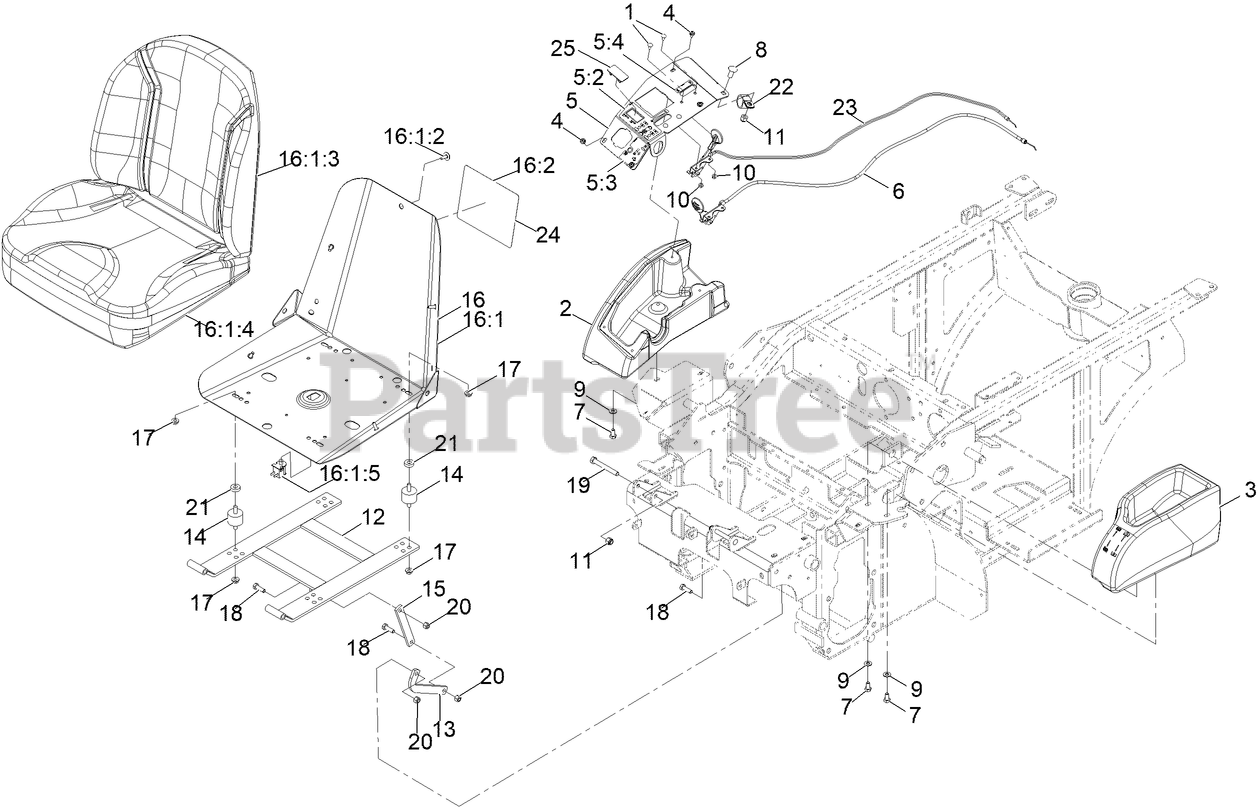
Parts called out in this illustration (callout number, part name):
1	BOLT-CARR
2	CONSOLE-RH
3	CONSOLE, LH GREY
4	SCREW-PPH
5	CONTROL PANEL ASM
5:2	Decal-Nav Console 640Kc
5:3	DECAL-SPEED CONTROL
5:4	DECAL-CHOKE
6	CABLE-THROTTLE
7	SCREW-HH
8	SCREW-CARR
9	WASHER-PLAIN
10	NUT-LOCK, NI
11	NUT-LOCK, NI
12	FRAME-SEAT
13	LINK-SEAT STOP
14	MOUNT-VIBRATION, RUBBER
15	LINK-SEAT
16	ASM-SEAT W/DECAL
16:1	ASM-Seat, Navigator
16:1:2	BOLT-SEAT
16:1:3	CUSHION-SEAT, BACK
16:1:4	COVER-SEAT BOTTOM SVC
16:1:5	SWITCH-BAIL
16:2	Decal-Service Aid
18	SCREW-HH
19	SCREW-HH
20	NUT-LOCK, NI
21	SPACER
22	CLIP-LOOM
23	ASM, CHOKE CABLE
24	Decal-Service Aid
25	PLUG-HOLE
